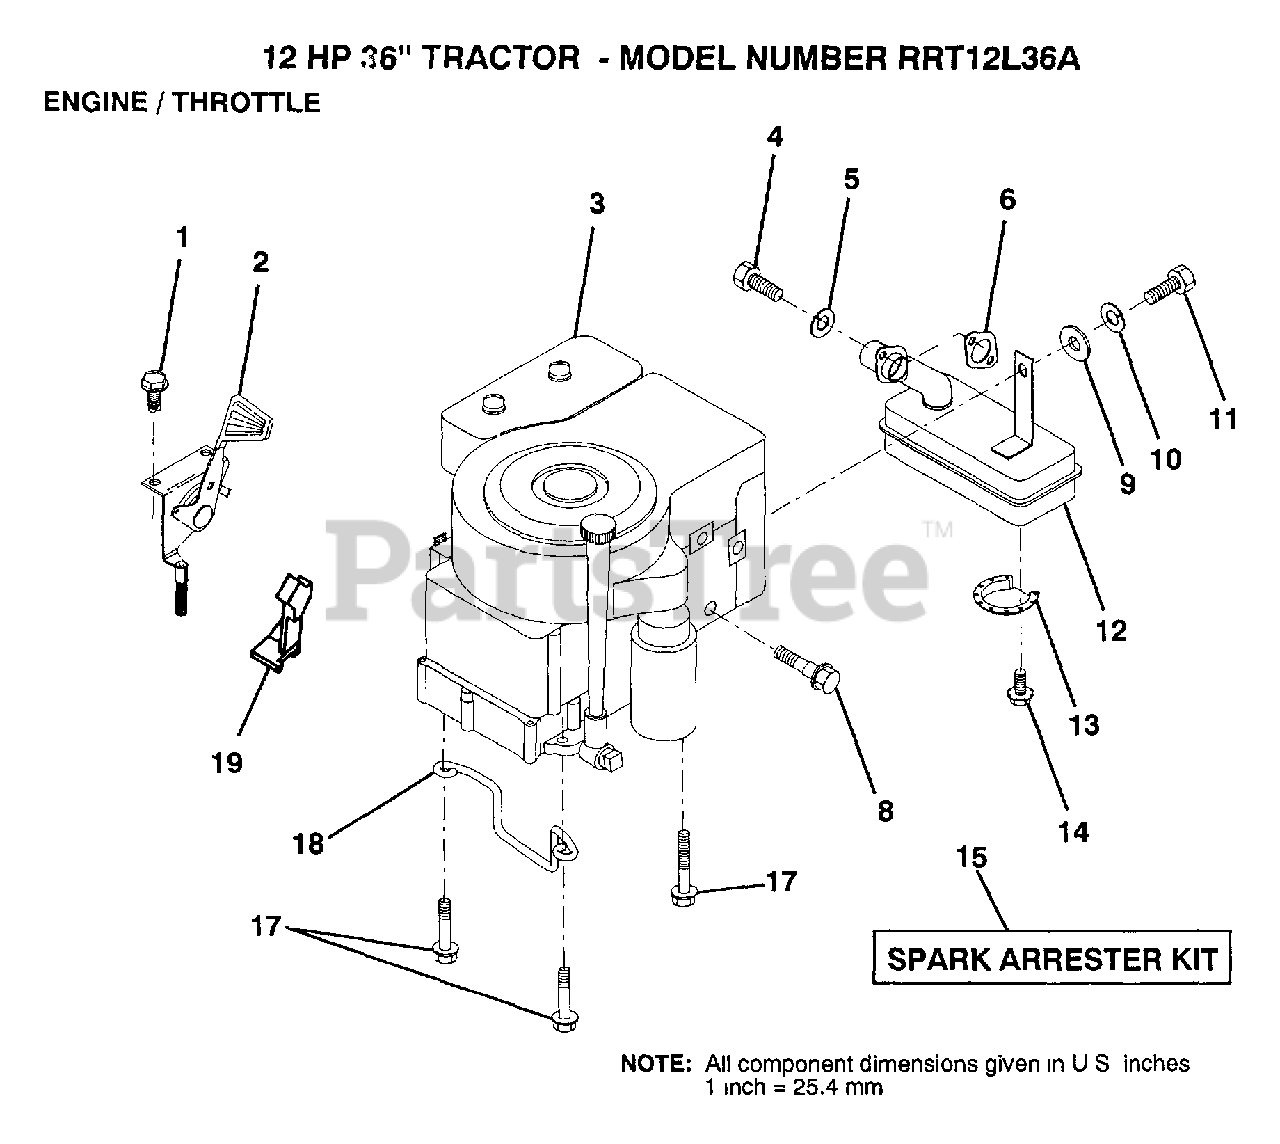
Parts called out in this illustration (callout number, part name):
1	SCREW
2	THROTTLE CONTROL
4	SCREW HEX HD CAP
5	LOCKWASHER
8	BOLT T
10	LOCKWASHER
13	DEFLECTOR.222573
17	SCREW LT
18	"KEEPER,DR BELT GR"
19	"STEP,CHOKE"
